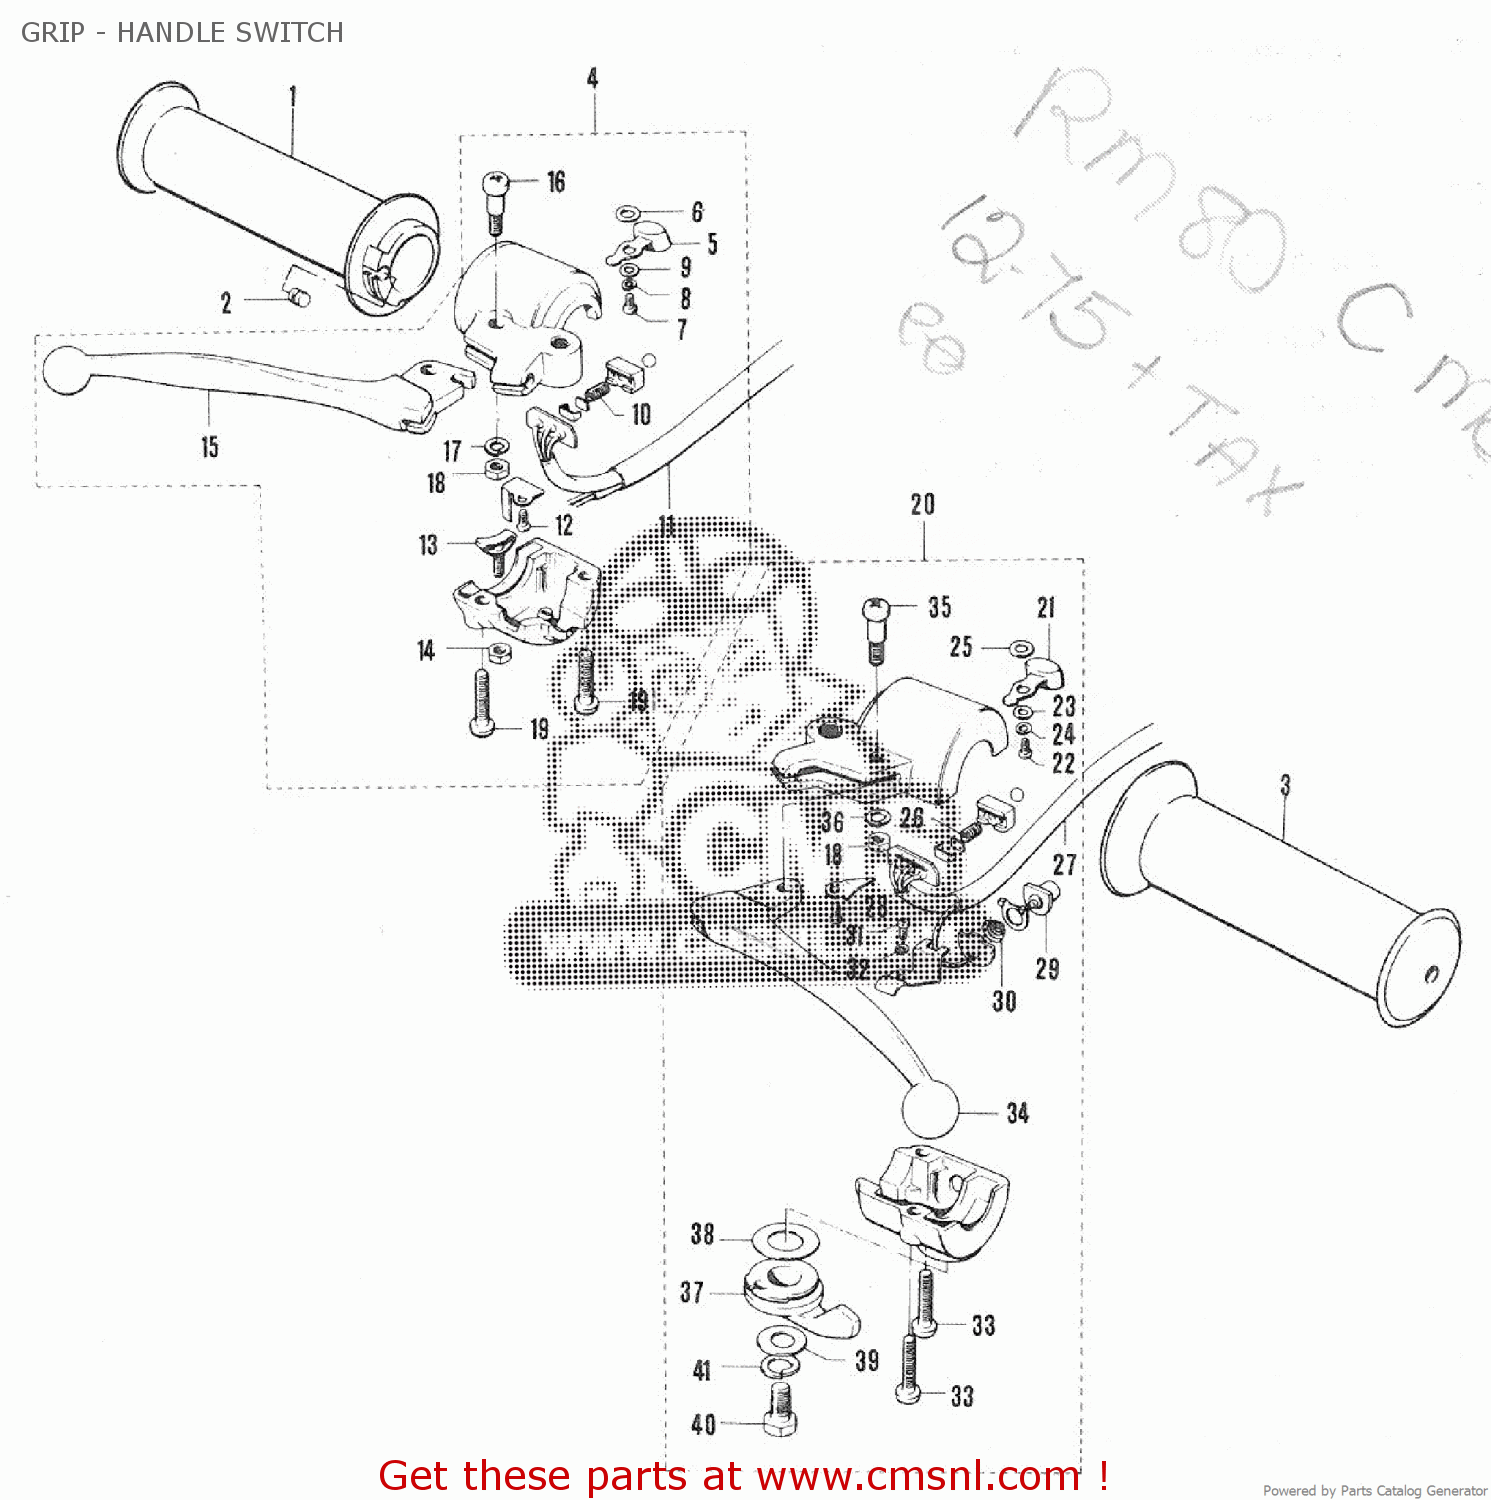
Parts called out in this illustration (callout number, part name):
1	GRIP,THROTTLE
2	PIECE,THROTTLE END
3	GRIP
4	LEVER/SWITCH ASSEMBLY,BRAKE
5	KNOB,DIMMER SWITCH
6	WASHER,DIM SWITCH KNOB
7	SCREW
8	LOCK WASHER
9	WASHER
10	SPRING,TURN SIGNAL SWITCH CONTACT
11	WIRING HARNESS
12	SCREW
13	ADJUSTER,GRIP
14	NUT
15	LEVER,BRAKE
16	BOLT,LEVER
17	LOCK WASHER
18	NUT
19	SCREW
20	LEVER ASSEMBLY
21	KNOB,DIMMER SWITCH
22	SCREW
23	WASHER
24	LOCK WASHER
25	WASHER,DIM SWITCH KNOB
26	SPRING,TURN SIGNAL SWITCH CONTACT
27	WIRING HARNESS
28	SCREW
29	BUTTON
30	SPRING
31	SCREW
32	LOCK WASHER
33	SCREW
34	LEVER,CLUTCH
35	BOLT,LEVER
36	LOCK WASHER
37	LEVER,STARTER
38	WASHER,ADJUSTER
39	WASHER,STARTER LEVER
40	BOLT
41	LOCK WASHER
